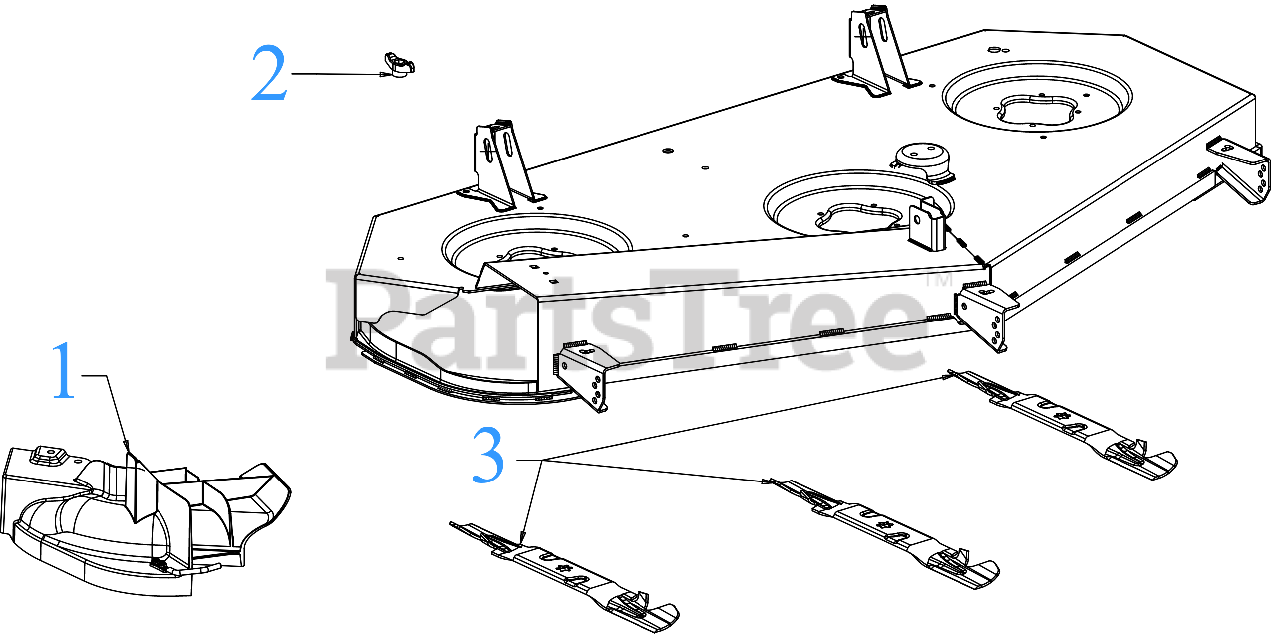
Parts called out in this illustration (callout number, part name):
1	MULCH PLUG ASSEMBLY
2	WING KNOB 5/16-18
3	60" EXTREME BLADE
